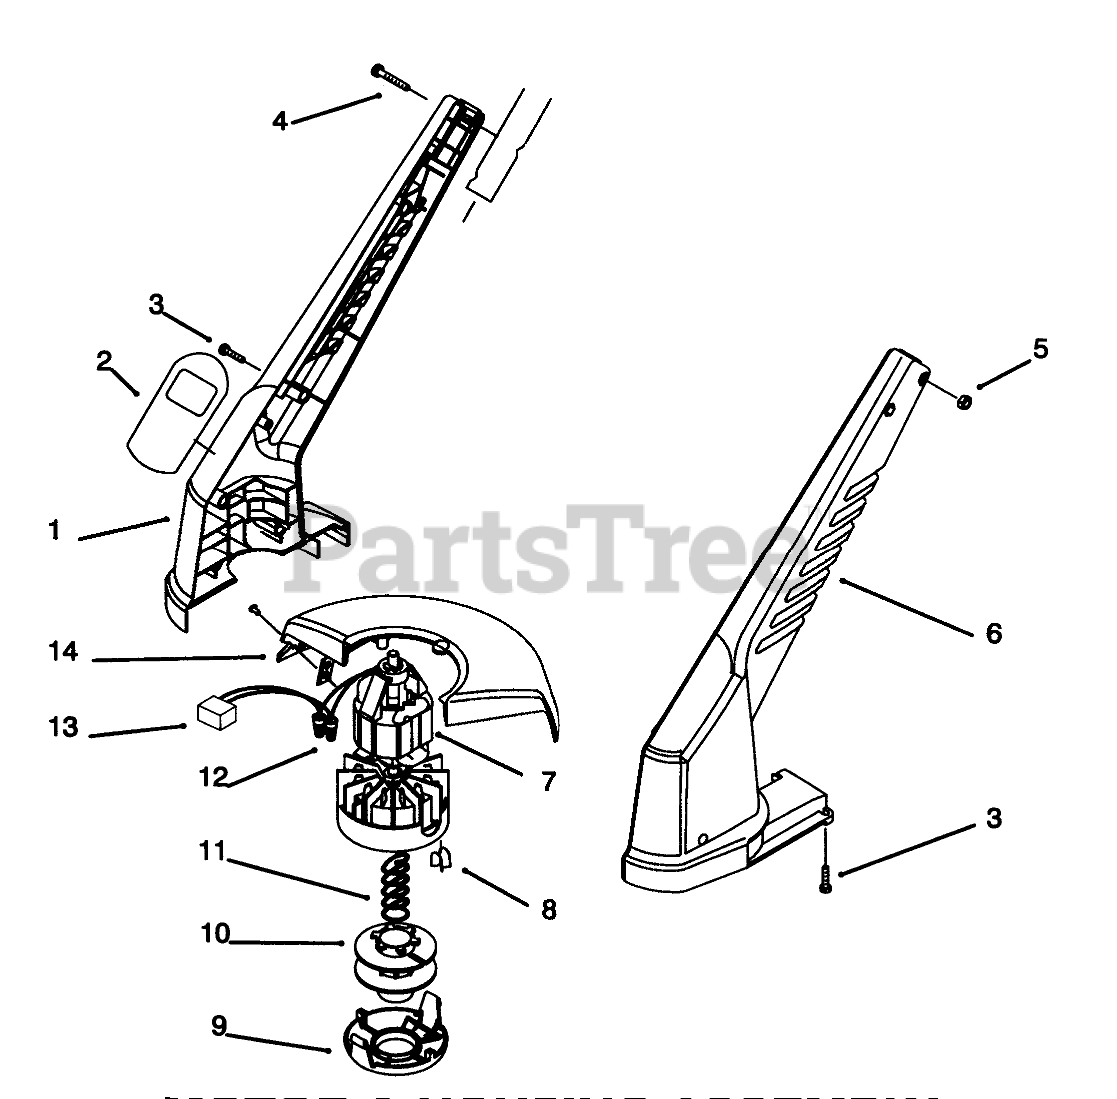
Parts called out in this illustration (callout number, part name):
1	HOUSING RH - TRIMMER, EUO
2	Decal-30CM Trimmer
3	Screw
4	SCREW-PPH
5	NUT-HEX
6	HOUSING LH - TRIMMER
7	Motor-Trimmer (Incl. Ref.#8)
8	EYELET
10	SPOOL-LARGE
11	SPRING-COMPRESSION
12	CONNECTOR-NUT, WIRE
13	FILTER - RFI
14	SHIELD ASM
